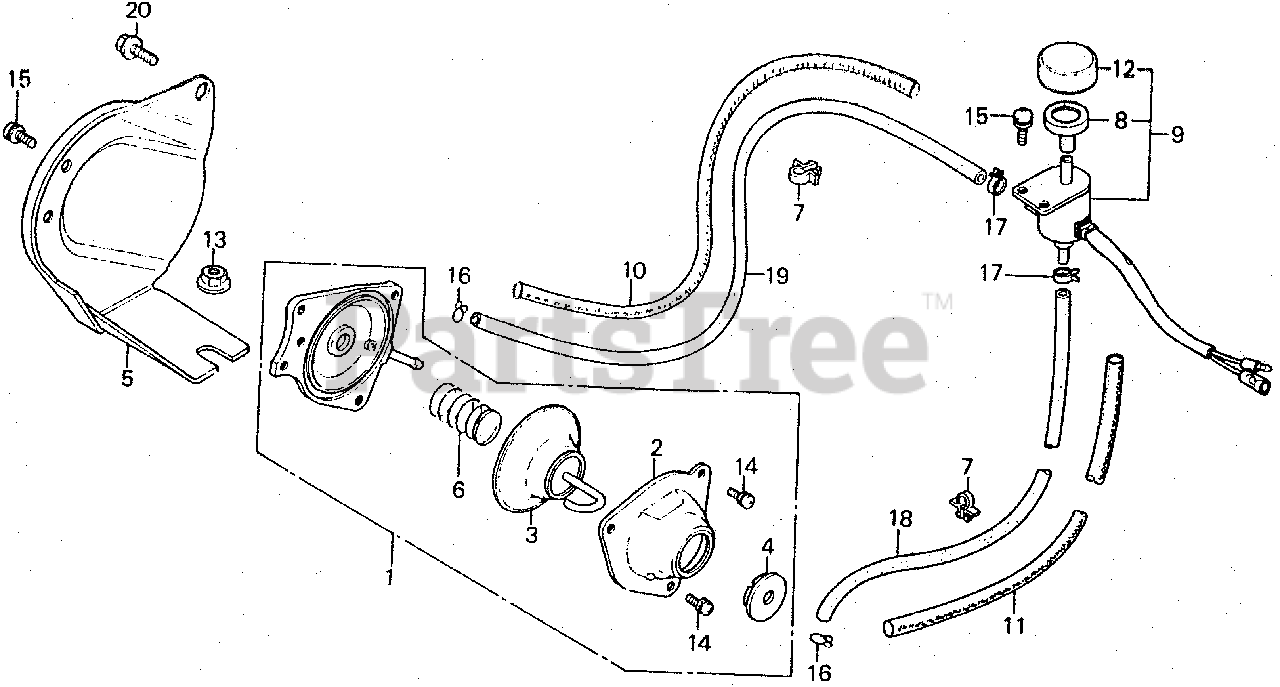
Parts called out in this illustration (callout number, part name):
1	DIAPHRAGM ASSY. (NOT AVAILABLE)
2	COVER, DIAPHRAGM
4	BUSH, DIAPHRAGM COVER
5	STAY, DIAPHRAGM
6	SPRING, COIL
7	CLIP, IGNITION WIRE (8MM)
8	FILTER ASSY., SOLENOID VALVE
9	VALVE ASSY., CONTROL
10	TUBE (8X680)
11	TUBE (8X470)
12	CAP, AIR FILTER
13	NUT, FLANGE (8MM)
14	SCREW-WASHER (4X8)
15	SCREW-WASHER (5X12)
16	CLIP, TUBE (B7)
17	CLAMP, TUBE (D8)
18	BULK HOSE, VACUUM (3.5X1000) (3.5X490)
19	BULK HOSE, VACUUM (3.5X1000) (3.5X700)
20	BOLT, FLANGE (8X16)
